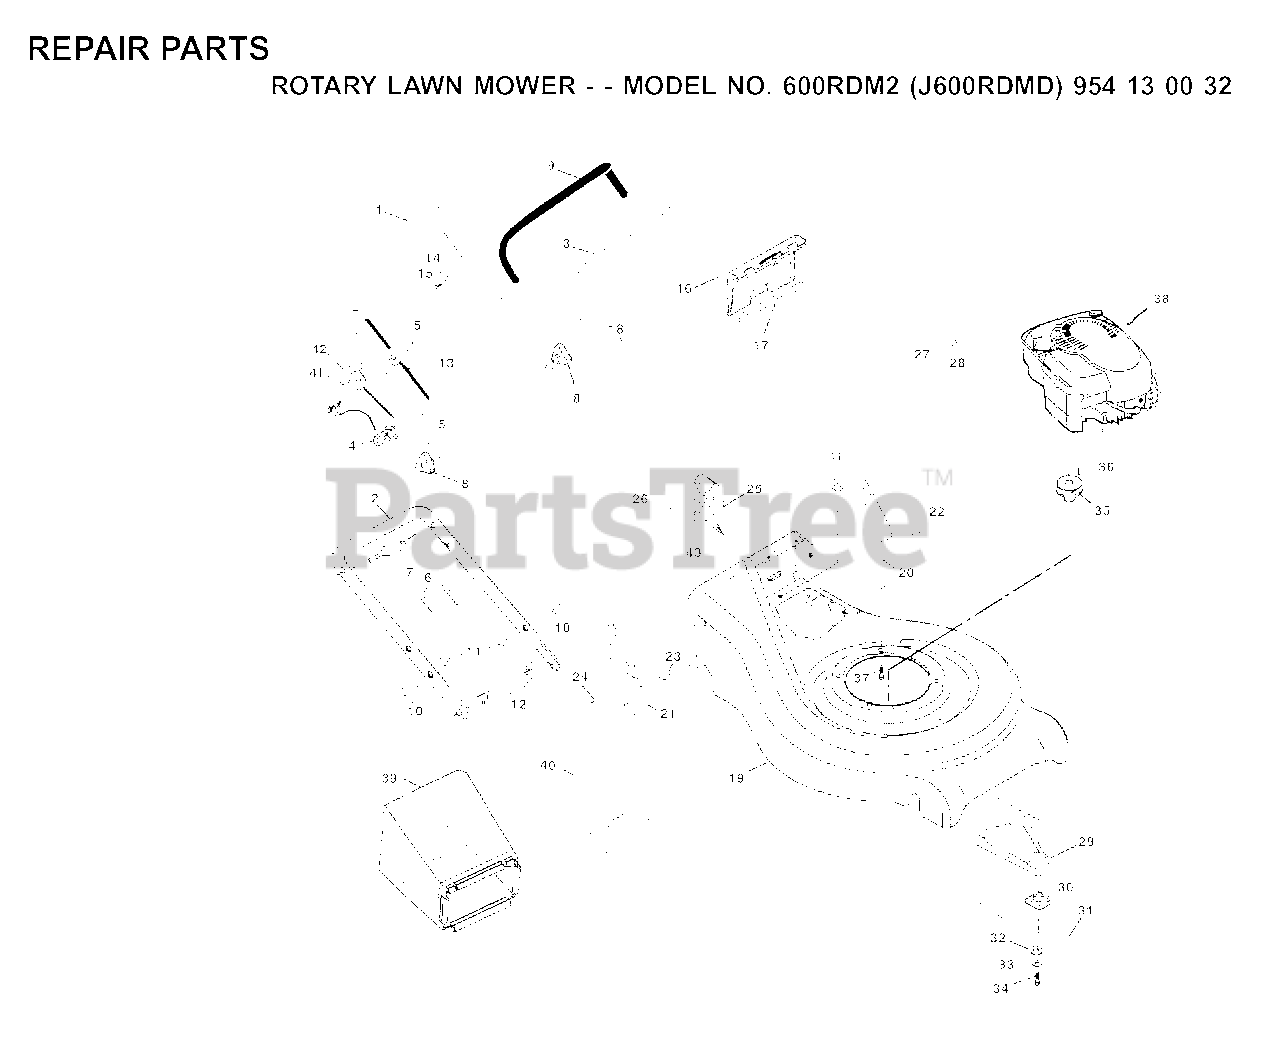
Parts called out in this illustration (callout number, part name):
2	HANDLE
3	CONTROL BAR
4	ROPE GUIDE
5	NUT
6	TIE GUIDE
7	HANDLE BOLT
9	GRIP.HANDLE.FOAM
10	BOLT
11	NUT
12	HAIRPIN COTTER
13	ENGINE ZONE CONTROL
14	BRACKET UPSTOP
15	SCREW.HEX.HEAD.WASHER.10-16
16	REAR DOOR KIT
17	SEALING
18	MULCH PLUG
20	.RACKET
22	SELF-TAPPING SCREW 5/16-18X3/4
23	BOLT, HEX HEAD 5/16-18
25	CLIPPING DEFLECTOR
27	SCREW.HEX.HEAD.WASHER.10-16
28	CABLE CLAMP(ENGINE)
29	DEBRIS SHIELD
30	RP BLADE ADAPTOR
31	21" MULCH BLADE PREMIUM
32	WASHER,HARDEN
33	LOCKWASHER
34	SCREW, HEX HD 3/8-24 X 1-3/8
35	ENGINE.PULLEY.FWG
36	HI PRO KEY PM
37	BOLT 3/8-16X1-1/8
40	GRASS CATCHER FRAME
41	SCREW 1/4-20 X 2.12
42	THROTTLE TRIGGER
43	DECAL MOWER CUT/FINGER
